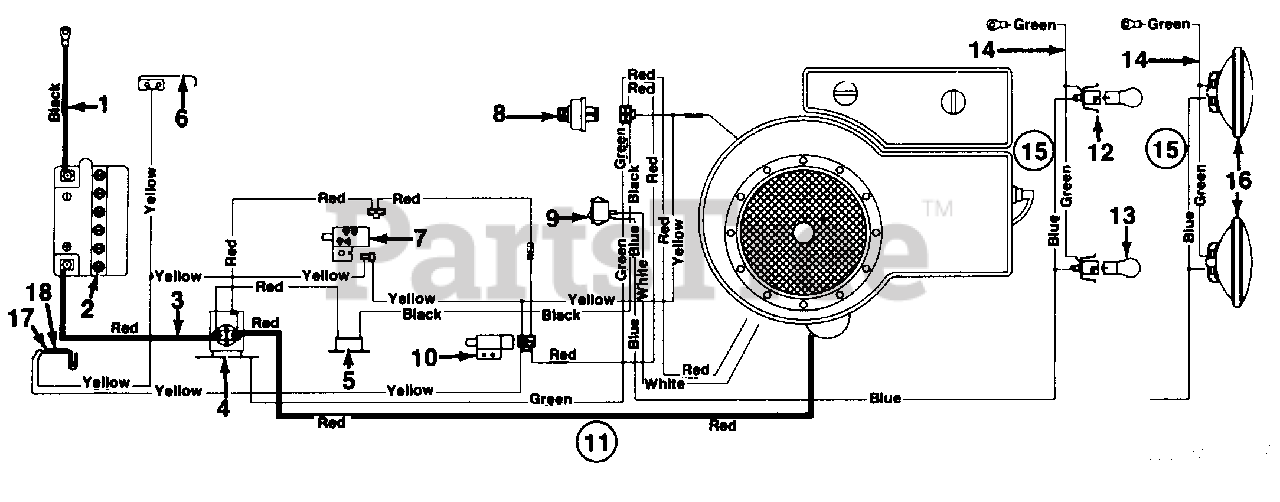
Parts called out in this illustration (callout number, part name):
1	Ground Wire
2	Battery
3	Electric Wire-8.0" Lg.
4	Solenoid
5	Circuit Breaker
6	Spring Switch
7	Safety Switch
8	Ignition Switch
9	Light Switch
10	Safety Switch
11	Harness
12	Socket
13	Bulb
14	Ground Wire
15	Headlight Harness
16	Headlight
17	Safety Switch
18	Safety Switch
